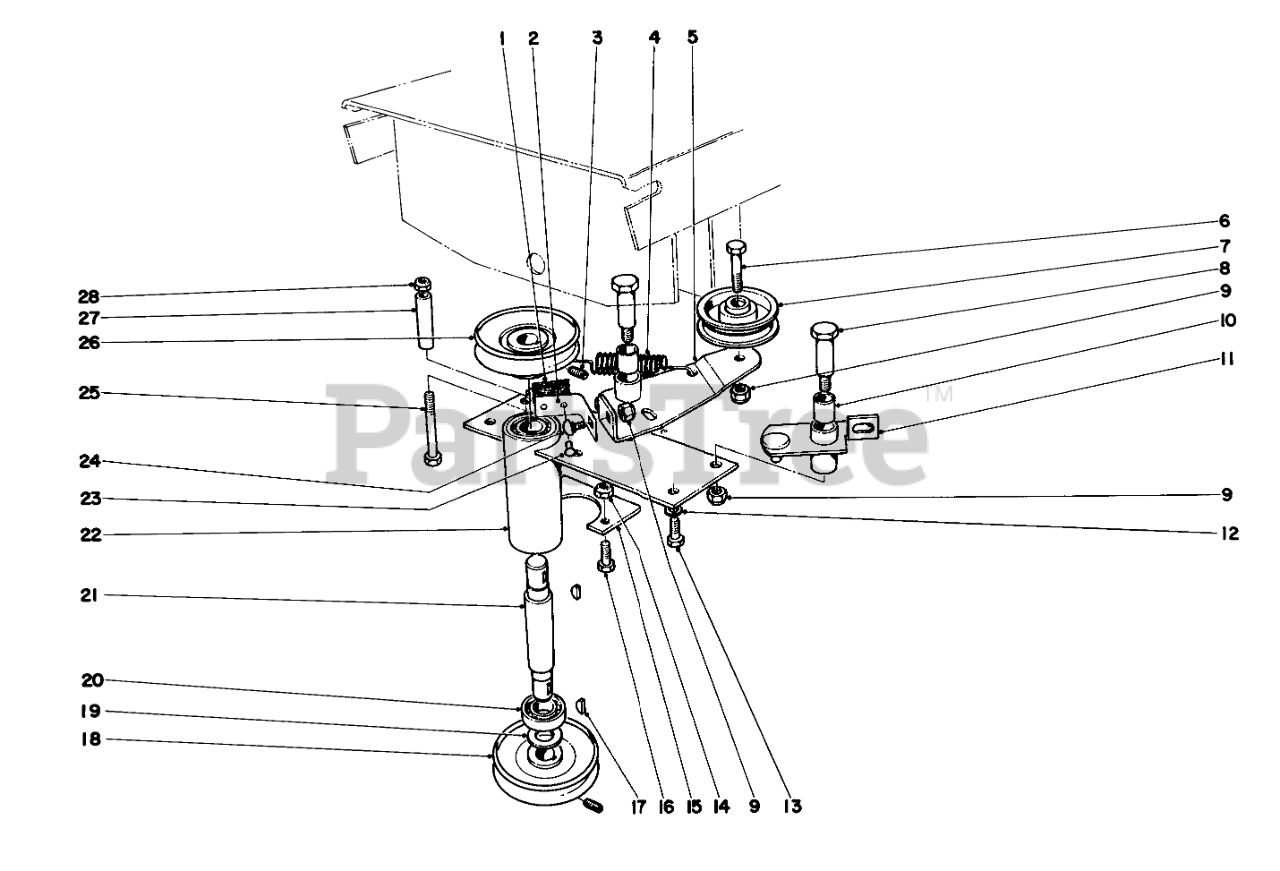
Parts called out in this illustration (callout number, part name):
1	BLADE BRAKE LINING
2	Brake Spring
3	SCREW-SET
4	Spring
5	Idler Plate
6	SCREW-HH
7	PULLEY-IDLER
8	Shoulder Bolt
9	NUT-LOCK, CONE
10	BUSHING
11	Pivot Bracket Incl. Ref. #10
12	WASHER-LOCK
13	SCREW-HH
14	NUT-LOCK, CONE
15	Retainer P.T.0. Tube
16	SCREW-HH
17	KEY-WOODRUFF
18	Pulley
19	Bearing Washer
20	Bearing
21	Shaft
22	P.T.0. Tube
23	Rivet
24	SCREW-CARR
25	SCREW-HH
26	Pulley
27	Spacer
28	NUT-LOCK, CONE
